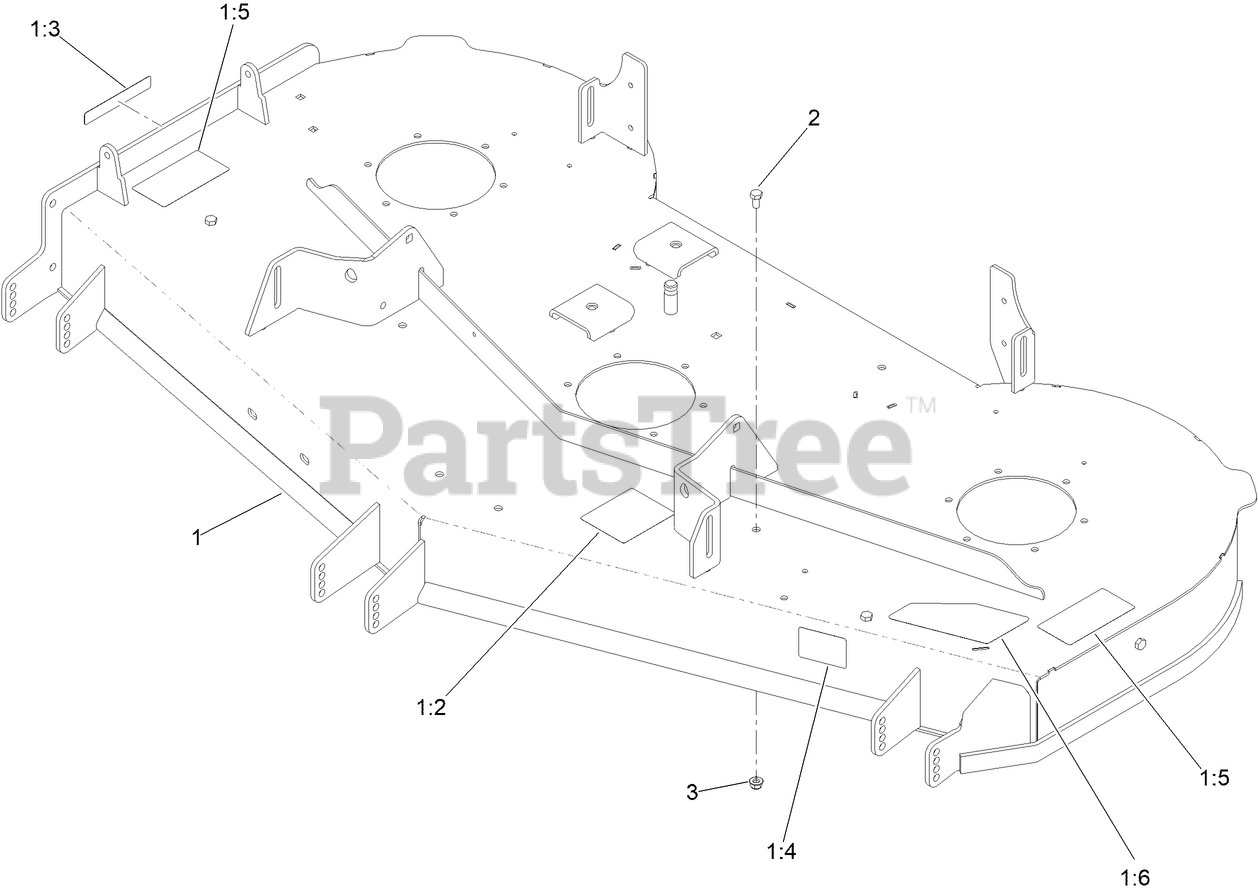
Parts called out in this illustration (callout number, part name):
1:2	DECAL-ROUTING, BELT
1:3	DECAL-DANGER
1:4	DECAL-SCALP, ANTI
1:5	DECAL-DANGER, DECK
1:6	DECAL-DECK
2	SCREW-HH
3	NUT-HF, NI
